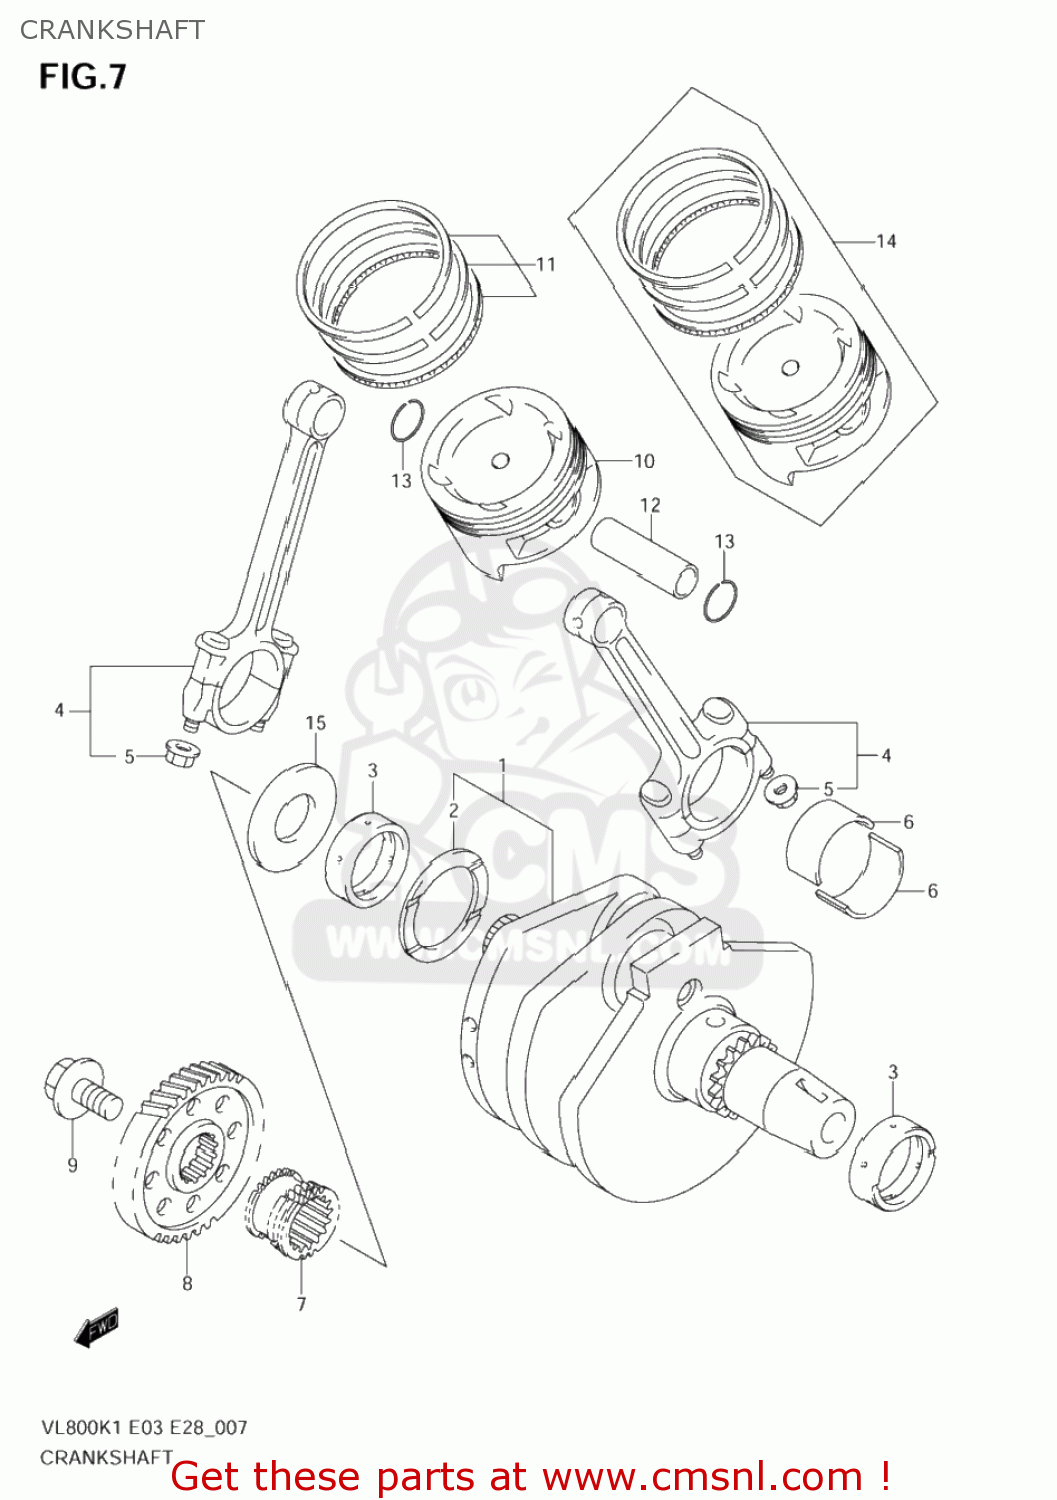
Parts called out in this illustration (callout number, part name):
1	CRANKSHAFT SET
2	WASHER(48.1X64X1.94)
3	METAL,CRANKSHAFT
4	CONNECTING ROD ASSY
5	NUT
6	BEARING,CRANK PIN
7	SPROCKET,CAM CHAIN DRIVE,R
8	GEAR,PRIMARY DRIVE
9	BOLT(12X28)
10	PISTON
11	RING SET,PISTON
12	PIN,PISTON
13	CIRCLIP,PISTON PIN
14	PISTON SET,OS0
15	WASHER,CRANK THRUST
